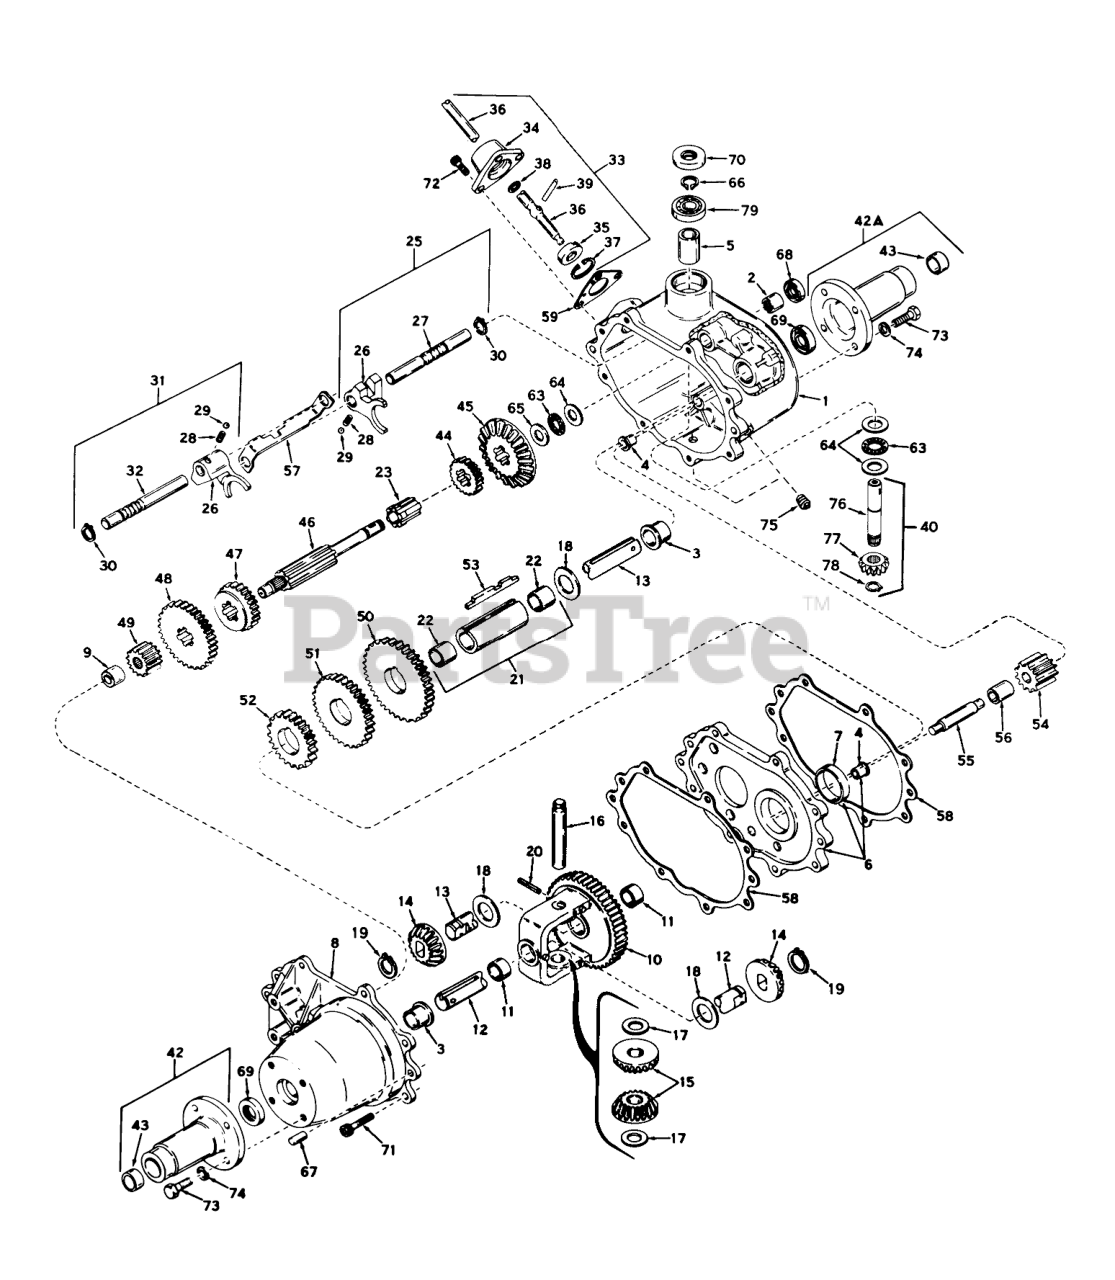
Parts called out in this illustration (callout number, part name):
1	Case Assy., Transaxle (Incl. Nos. 2 thru 5)
2	Bearing-Needle
3	Bronze Bearing
4	Bronze Bearing
5	Bronze Bearing
6	Plate Assy., Center (Incl. Nos. 4 & 7)
7	Bronze Bearing
8	Cover Assy., Transaxle (Incl. Nos. 3 & 9)
9	Needle Bearing
10	Gear Assy., Differential (Incl. No. 11)
11	Bushing
12	Axle, Left Hand
13	Axle, Left Hand
14	Bevel Gear
15	Gear Pinion
16	Drive Pin
17	Thrust Washer
18	Washer
19	Snap Ring
20	Pin-Roll
21	Sleeve Assy., Countershaft (Incl. No. 22)
22	Bronze Bearing
23	Shaft, Idler
25	Rod Assy., Shift (1st & Rev.) (Incl. Nos. 26 thru 30)
26	Shift Fork
27	Shift Rod
28	Piston ASM
29	Piston ASM
30	Ring-Snap
31	Rod Assy., Shift (2nd & 3rd) (Incl. Nos. 26, 28, 29, 30 & 32)
32	Shift Rod
33	Lever & Housing Assy., Shift (Incl. Nos. 34 thru 39)
34	Shift Lever Housing
35	Keeper-Shift Lever
36	Lever, Shift
37	Ring-Snap
38	O Ring
39	Roll Pin
40	Shaft & Gear Assy., Input (Incl. Nos. 76, 77 & 78)
42	Housing Assy., Axle (Incl. No. 43)
42A	Housing Assy., Axle (Incl. No. 43)
43	O Ring
44	Gear (10 teeth)
45	Bevel Gear (33 teeth)
46	Shaft, Shifter & Brake
47	Gear, Shifting (2nd & 3rd)
48	Gear, Shifting (1st & Rev.)
49	Spur Gear (12 teeth)
50	Countershaft Drive Gear (39 teeth)
51	Gear (34 teeth)
52	Countershaft Gear (25 teeth)
53	Key, Countershaft
54	Reverse Idler
55	Reverse Idler Shaft
56	Reverse Idler Spacer
57	Shifter Stop
58	Gasket, Case & Cover
59	Shift Lever Housing Gasket
63	Bearing-Thrust
64	Washer
65	Washer, Thrust
66	Ring-Snap
67	Dowel Pin
68	Seal, Oil
69	Oil Seal
70	Oil Seal
71	Ring-Retaining
72	Screw, Socket Hd. Cap
73	Screw-Hex Hd.
74	Lockwasher
75	Plug-Pipe
76	Shaft, Input
77	Pinion, Input
78	Ring-Retainer
79	Bearing, Ball
